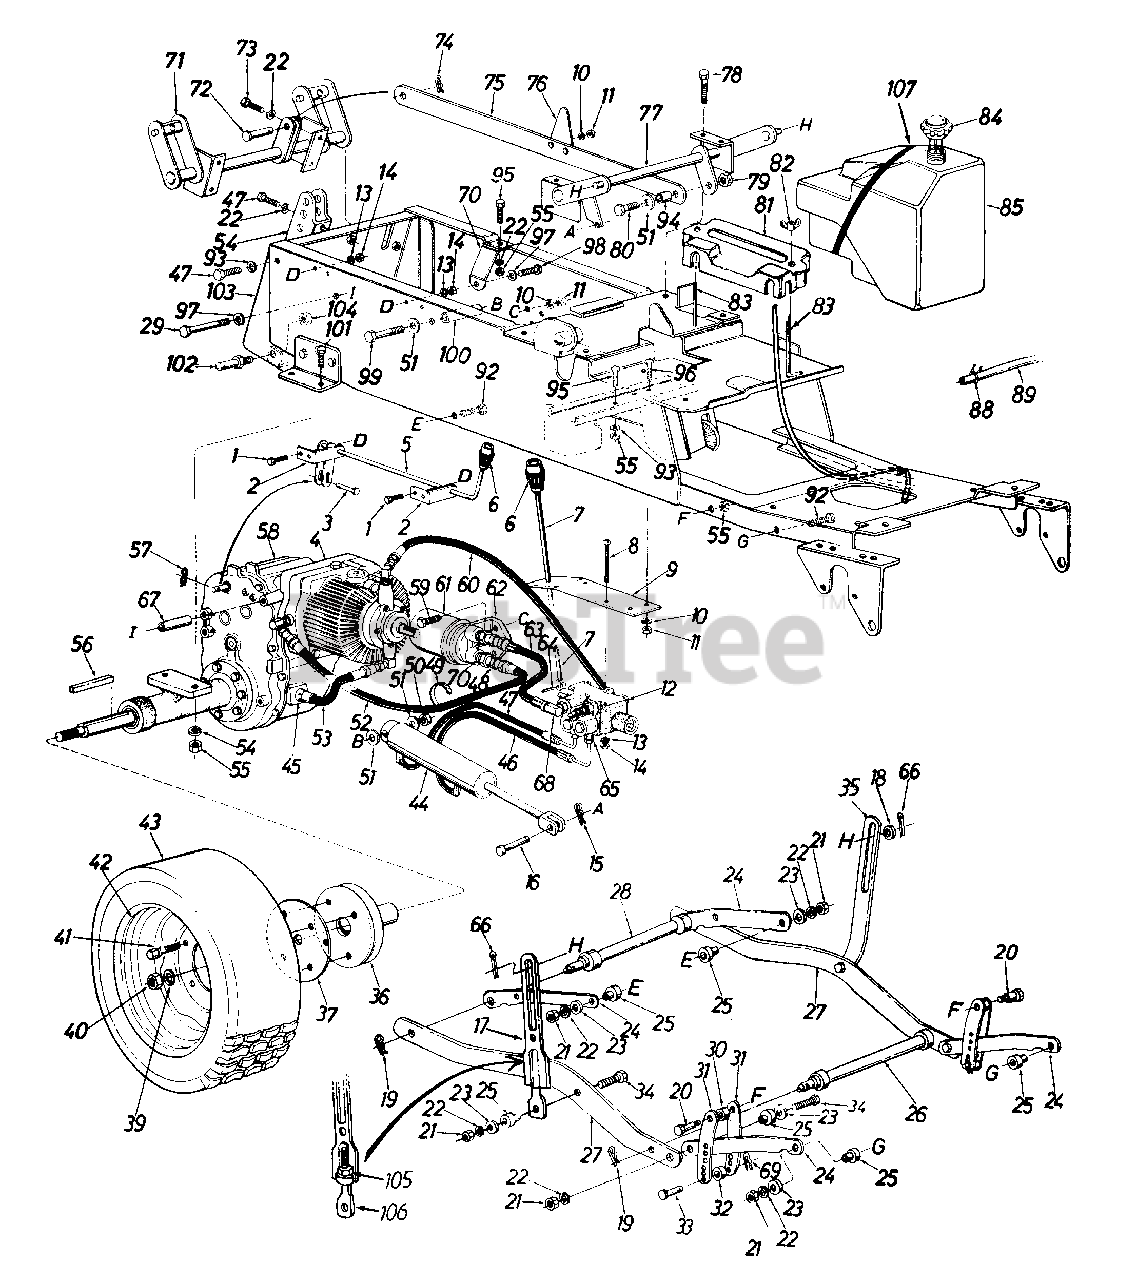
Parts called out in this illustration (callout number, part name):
1	Hex Bolt 1/4-20 x .75" Lg.
4	Hydrostatic Pump Comp.
5	Hi-Lo Control Handle Ass'y.
6	Shift Knob
7	Cylinder Control Handle Ass'y.
8	Truss Mach. Scr. 1/4-20 x 3.00" Lg.
11	Hex Nut 5/16-18 Thd.
12	Valve Ass'y. Comp.
13	L-Wash. 1/4" I.D.
14	Hex Nut 1/4-20 Thd.
15	Hairpin Cotter 1/2" Dia.
16	Clevis Pin 1/2" Dia..
17	Adj. Deck Link
18	Fl-Wash. .62" I.D. x 1.12"
19	Hairpin Cotter
20	Shld. Bolt .498" Dia. x .66"
21	Hex Nut 3/8-24 Thd.
22	L-Wash. 3/8" I.d.-H.D.
23	Fl-Wash. .38" I.D. x 1.00"
26	Cross Shaft Ass'y.-Front
29	Hex Bolt 1/2-13 x 2.75"
30	Collar .50" I.D. x 1.0"
33	Clevis Pin 3/8" Dia.
34	Hex Bolt 3/8-24 x 1.50" Lg.-Grade 5
39	L-Wash. 3/4" I.D.
40	Hex Ins. L-Nut 3/4-16 Thd.
41	Wheel Lug Bolt
44	Hydraulic cylinder
45	7/8-14 UNF-2A Thd. 5/8 Tube Fitting
46	Valve to Cylinder Hose-20"
47	Hex Bolt 3/8-16 x .75" Lg.-Grade 5
48	Bushing Reducer 1/2-14 NPTF to 3/8-18 NPTF
49	Cable Tie
50	Hex Jam Nut 1/2-20 Thd.
51	Fl-Wash. .50" I.D. x 1.25
52	Filter Return Hose 24" Lg.
53	Pump Tube Ass'y.
55	hex Nut 3/8-16 Thd.
56	Sq. key 1/4" x 1/4" x 2"
57	Hairpin Cotter 1/4" Dia.
58	Peerless Transaxle
59	Hex Bolt 5/16-18 x 1.25"
60	Pump to Valve Hose
61	Fram Filter Ass'y. PH-16
62	Filter Base
63	Valve to Filter Hose-8.38"
64	Spring Pin Spiral 1/8" Dia.
65	Flare Adapter
66	Cotter Pin 1/8" Dia. x 1.0"
67	Spacer
68	Adapter 9/16-18 to 9/16-18
69	Hairpin Cotter
70	Transmission Brace
73	Hex Scr. 3/8-16 x 1.00" Lg. Grade 5
74	Cotter Pin 1/8" Dia. x 1.25"
79	Hex Cent. L-Nut 1/2-20 Thd.
80	Hex Scr. 1/2-20 x 1.25" Lg.
81	Battery Cover
82	Wing Nut 1/4-20 Thd.
83	Battery Hold Down Rods
84	Gas Tank Cap
85	Gas Tank Ass'y.
88	Gas Line clamp 1/2"
89	Gas line 46" Lg.
92	Hex Scr. 3/8-24 x 1.50" Lg.
93	L-Wash. 3/8" Scr.
94	Push bar Sleeve
95	Hex Scr. 3/8-16 x 1.00" Lg.-Grade 5
96	Hex Scr. 5/16-18 x .75" Lg.
97	L-Wash. 1/2" Scr.
98	Hex Scr. 1/2-13 x 1.25" Lg.
99	Hex Scr. 1/2-20 x 3 1/2" Lg.-Grade 5
100	Spacer for cylinder
101	Hex Scr. 3/8-16 x 1.75" Lg.
102	link Clevis Pin
105	Hex Nut 1/2-13 Thd.
106	Eye Bolt
107	Tie Strap
